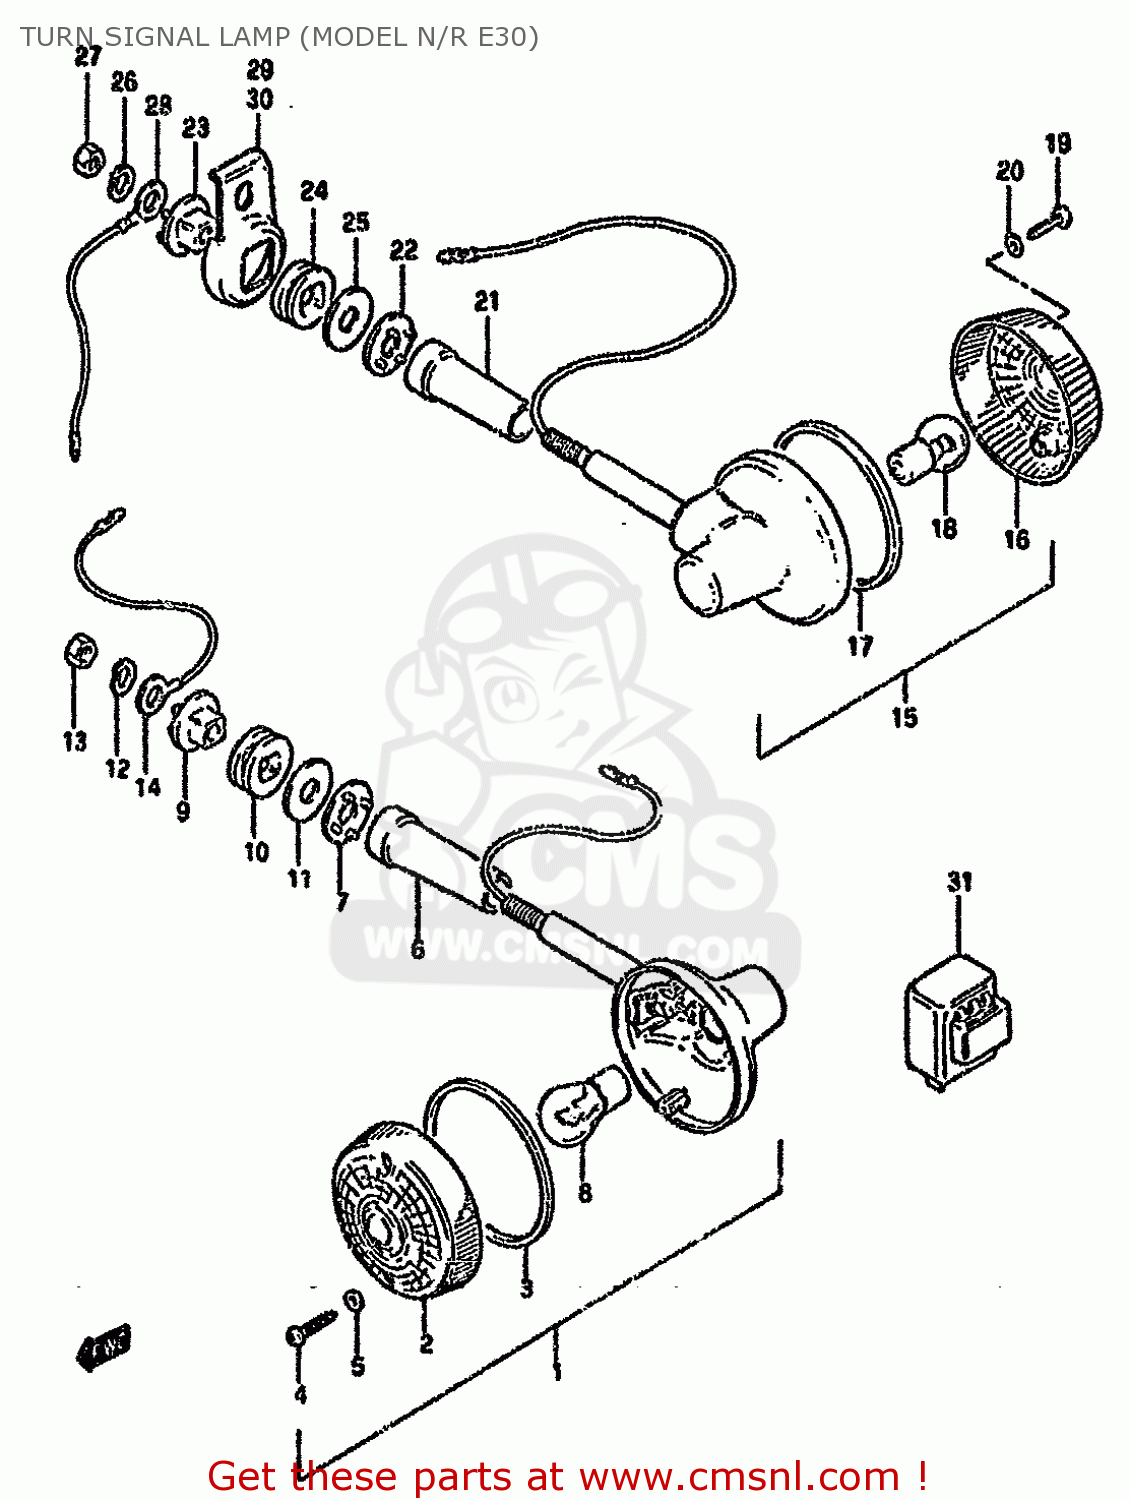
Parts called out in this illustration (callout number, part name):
1	LAMP ASSY,TURNSIGNAL
2	LENS
3	GASKET (NAS)
4	SCREW
5	GASKET (NAS)
6	COVER,STAY
7	SPACER
8	BULB(12V23W,STANLEY,A4577A)
9	SPACER
10	CUSHION
11	WASHER (10.5X30X2.3)
12	WASHER,LOCK,10
13	NUT
14	LEAD WIRE,EARTH
15	LAMP ASSY,RR TURNSIGNAL
16	LENS
17	GASKET (NAS)
18	BULB(12V23W,STANLEY,A4577A)
19	SCREW
20	GASKET (NAS)
21	COVER
22	SPACER
23	SPACER
24	CUSHION
25	WASHER (10.5X30X2.3)
26	WASHER,LOCK,10
27	NUT
28	LEAD WIRE,EARTH
29	BRACKET,RR TURNSIGNAL LAMP,R
30	BRACKET,RR TURNSIGNAL LAMP,L
31	RELAY ASSEMBLY,TURN SIGNAL
